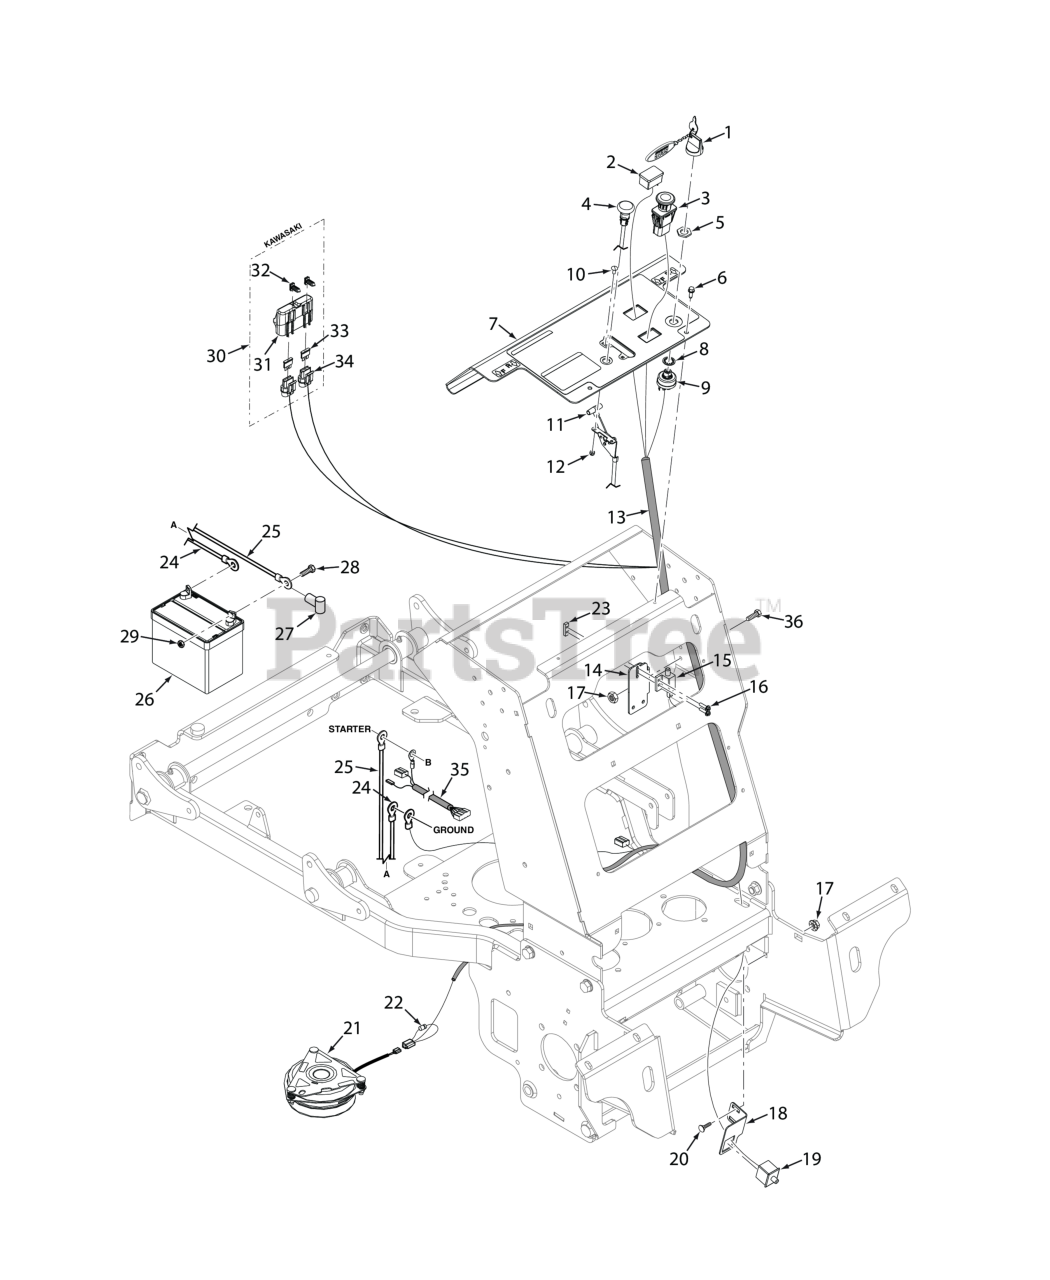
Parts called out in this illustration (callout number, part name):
1	Key, Assembly w/Fob
2	Hour Meter, Inductive
3	Switch, PTO - 10 Amp
4	Choke Control (excludes EFI models)
5	Nut, 5/8-32 Special
6	Screw, Self-Tapping 1/4-20 x 3/4
7	Instrument Panel w/Decal - SVRII36
8	LOCK WASHER, 5/8" INTERNAL TOOTH
9	KEY SWITCH(INCLUDES MOUNTING HARDWARE)
10	Bolt, Carriage #10-24 x 1/2"
11	Throttle Control, SVR
12	Nut, Elastic Stop #10-24
13	Wire Harness, SVRII-36
14	Bracket, Neutral Switch
15	Switch, Interlock (see below)
16	Screw, Hex-Slotted Washer Head #10 32 x 3/4"
17	NUT, 1/4-20 SERRATED FLANGE HEX HEAD
18	Switch Bracket, OPC Switch -SVRII-36
19	Switch, Double Pole OPC - SVRII-36
20	Serr. Fl. Hex Head CPSCR, 1/4-20 x 3/4"
21	Clutch w/Tag GT2.5-FE02 (48 / 52)
22	Diode, 600V 6 Amp
23	Plate, Threaded
24	Battery Cable, 39" Black (26EFI) - Kohler
25	Battery Cable, 44" Red w/Braid (26EFI) - Kohler
26	Battery, 350 CCA (not available through Scag)
27	RUBBER BOOT
28	BOLT, HEX HEAD, 1/4-20 X 3/4 GR.5
29	Nut, 1/4 - 20 Hex
30	Double Fuse Assy.
31	Cover, Sealed Double
32	Clip, Fuse Holder
33	FUSE, 20 AMP BLADE TYPE AUTOMOTIVE
34	Fuse Holder Assembly
35	Wire Harness Adapter, Kawasaki FX & FT
36	BOLT, HEX HEAD, 1/4-20 X 3/4 GR.5
